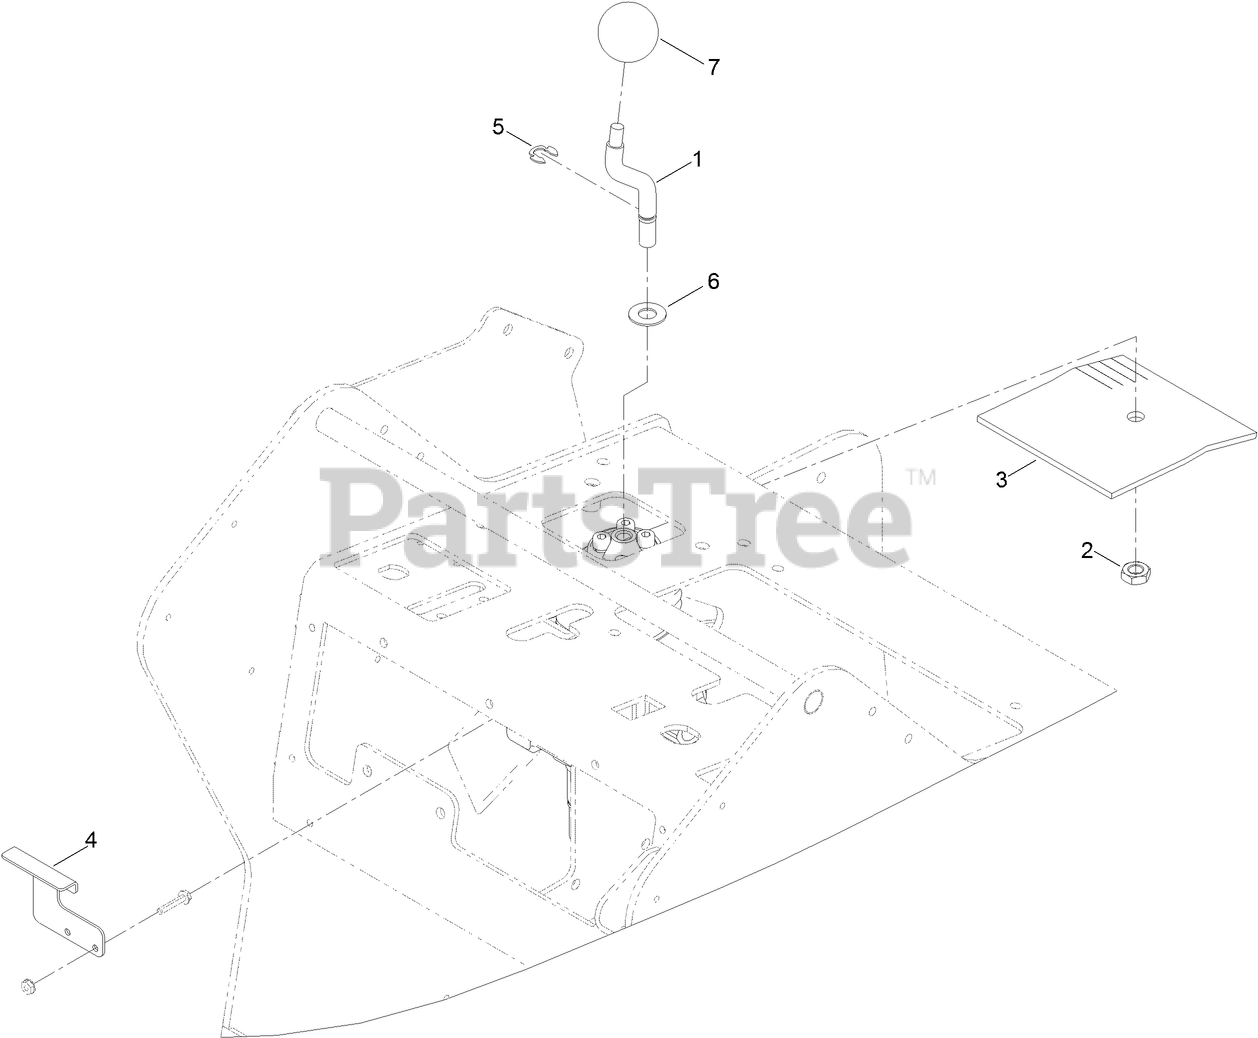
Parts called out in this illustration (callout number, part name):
1	SHAFT-HANDLE, LIFT/TILT
3	DEFLECTOR-AIR
4	BRACKET-DEFLECTOR
5	RING-RETAINING
6	WASHER-PIVOT
